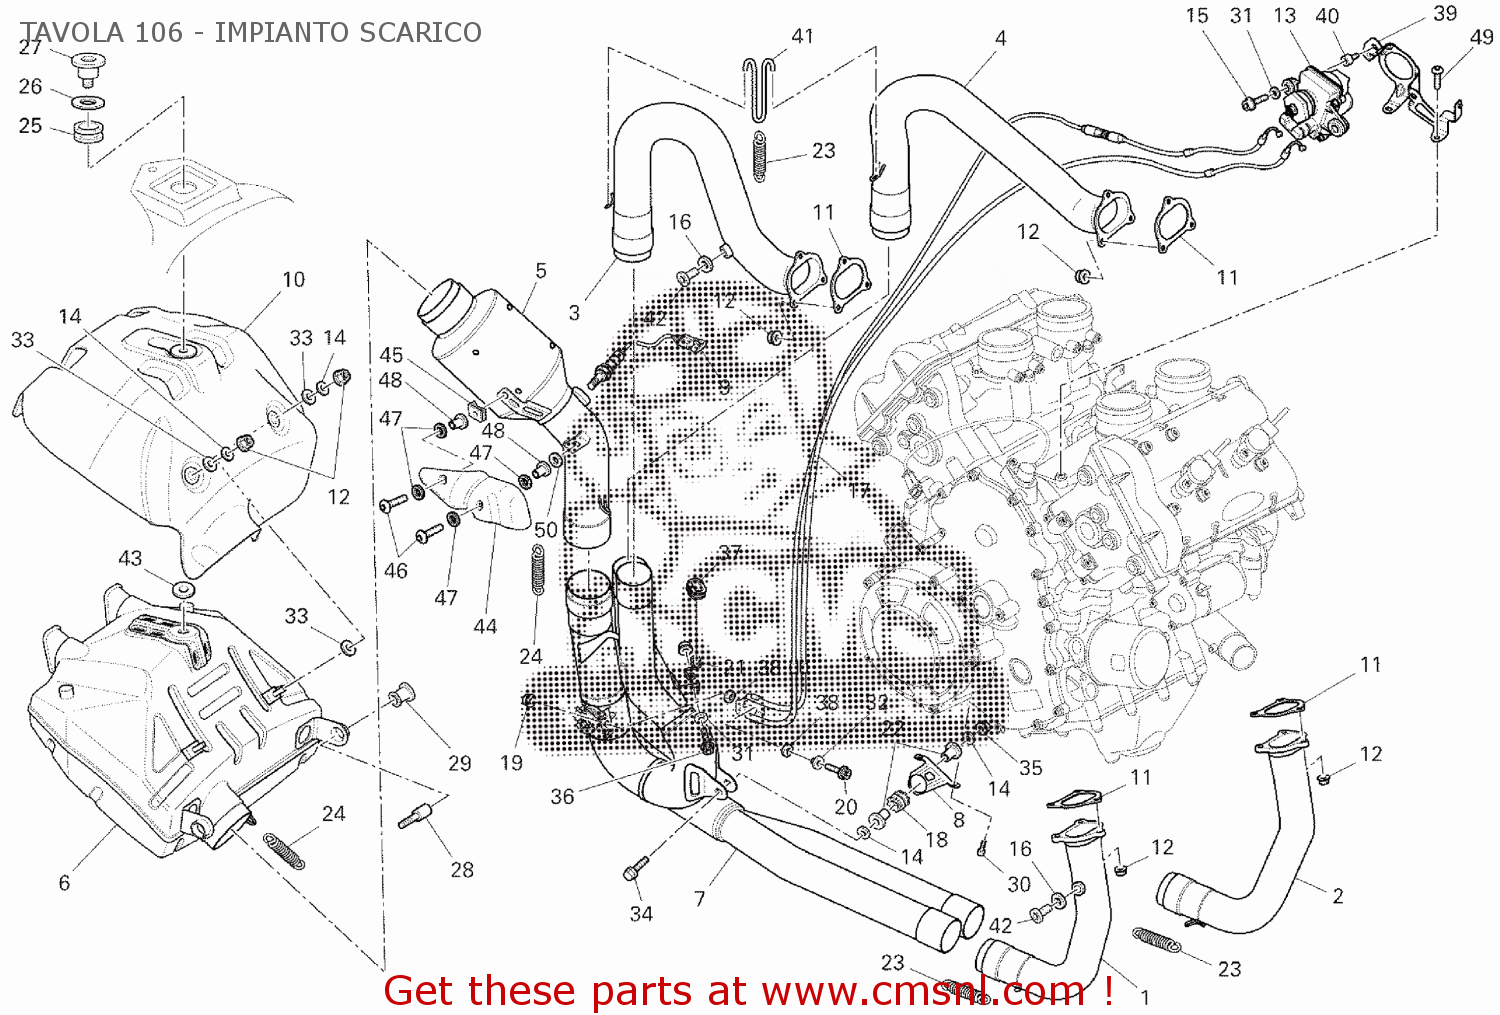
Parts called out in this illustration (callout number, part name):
1	EXHAUST PIPE, HORIZONTAL RH
2	EXHAUST PIPE, HORIZONTAL LH
3	EXHAUST PIPE, VERTICAL RH
4	EXHAUST PIPE, VERTICAL LH
5	PIPE, PRE-SILENCER
6	SILENCER
7	PIPE, EXHAUST CENTER
8	BRACKET
9	SENSOR LAMBDA SOND
10	PROTECTOR, HEAT
11	GASKET, EXHAUST PIPE
12	NUT
13	ELECTRIC MOTOR, EXHAUST VALVE
14	WASHER 6.4X16X0.5
15	SCREW TCEIF M6X20
16	WASHER 10X14X1
17	CABLE SET EXHAUST VALVE
18	VIBRATION DAMPER PAD
19	NUT
20	SCREW TCEIF M5X14
21	GUIDE, CABLE
22	SPACER 6.25X10X5.75
23	SPRING, EXHAUST PIPE
24	SPRING EXHAUST , LONG
25	VIBRATION DAMPER PAD
26	WASHER 28X12.2X0.5
27	SCREW, SPECIAL
28	SCREW, SPECIAL
29	RUBBER PAD
30	SCREW TC M6X16
31	WASHER 6.4X18X1
32	SPACER
33	WASHER 6X12X2
34	SCREW TEF M6X30
35	NUT 6MM
36	SCREW TCEIF M6X12
37	RUBBER PAD
38	SPRING WASHER
39	BRACKET ACTUATOR EXHAUST CONTROL
40	DAMPER
41	BRACKET
42	PLUG ASSY
43	SPACER,15X28X1
44	PROTECTOR, HEAT
45	QUICK FASTENING
46	SCREW TBEI M5X12
47	WASHER
48	SPACER 5.2X8.4X16
49	SCREW TBEI M6X16
50	WASHER 5.3X15X1
